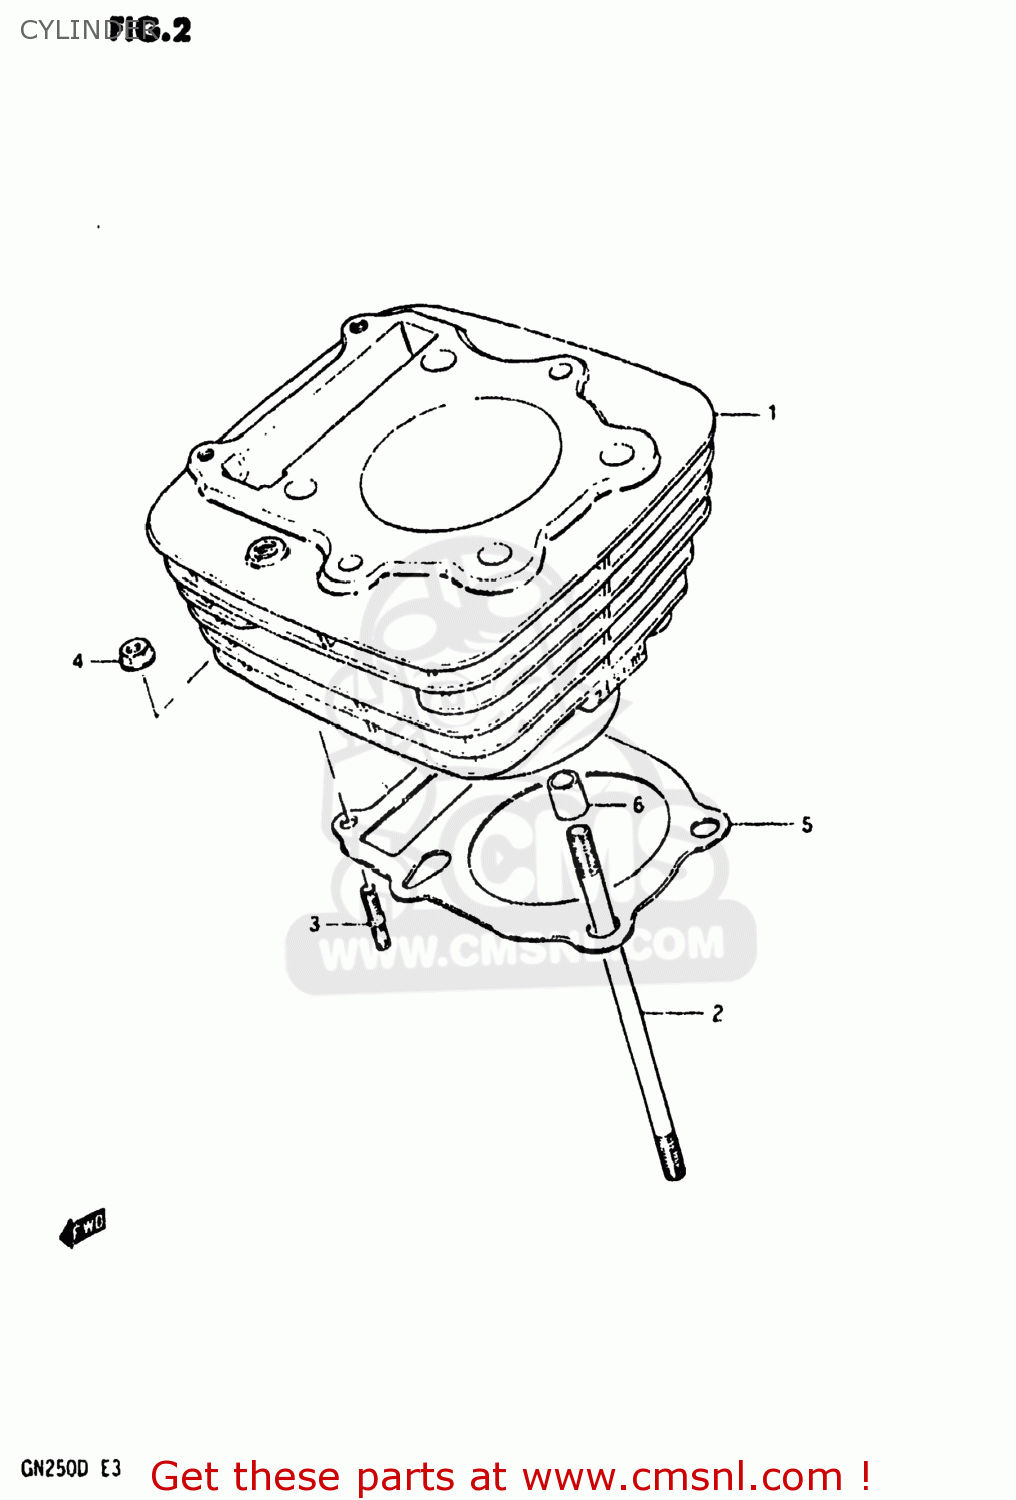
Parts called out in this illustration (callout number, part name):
1	CYLINDER
2	BOLT,STUD
3	STUD 6X25
4	NUT
5	GASKET,CYLINDER (MCA)
6	PIN
